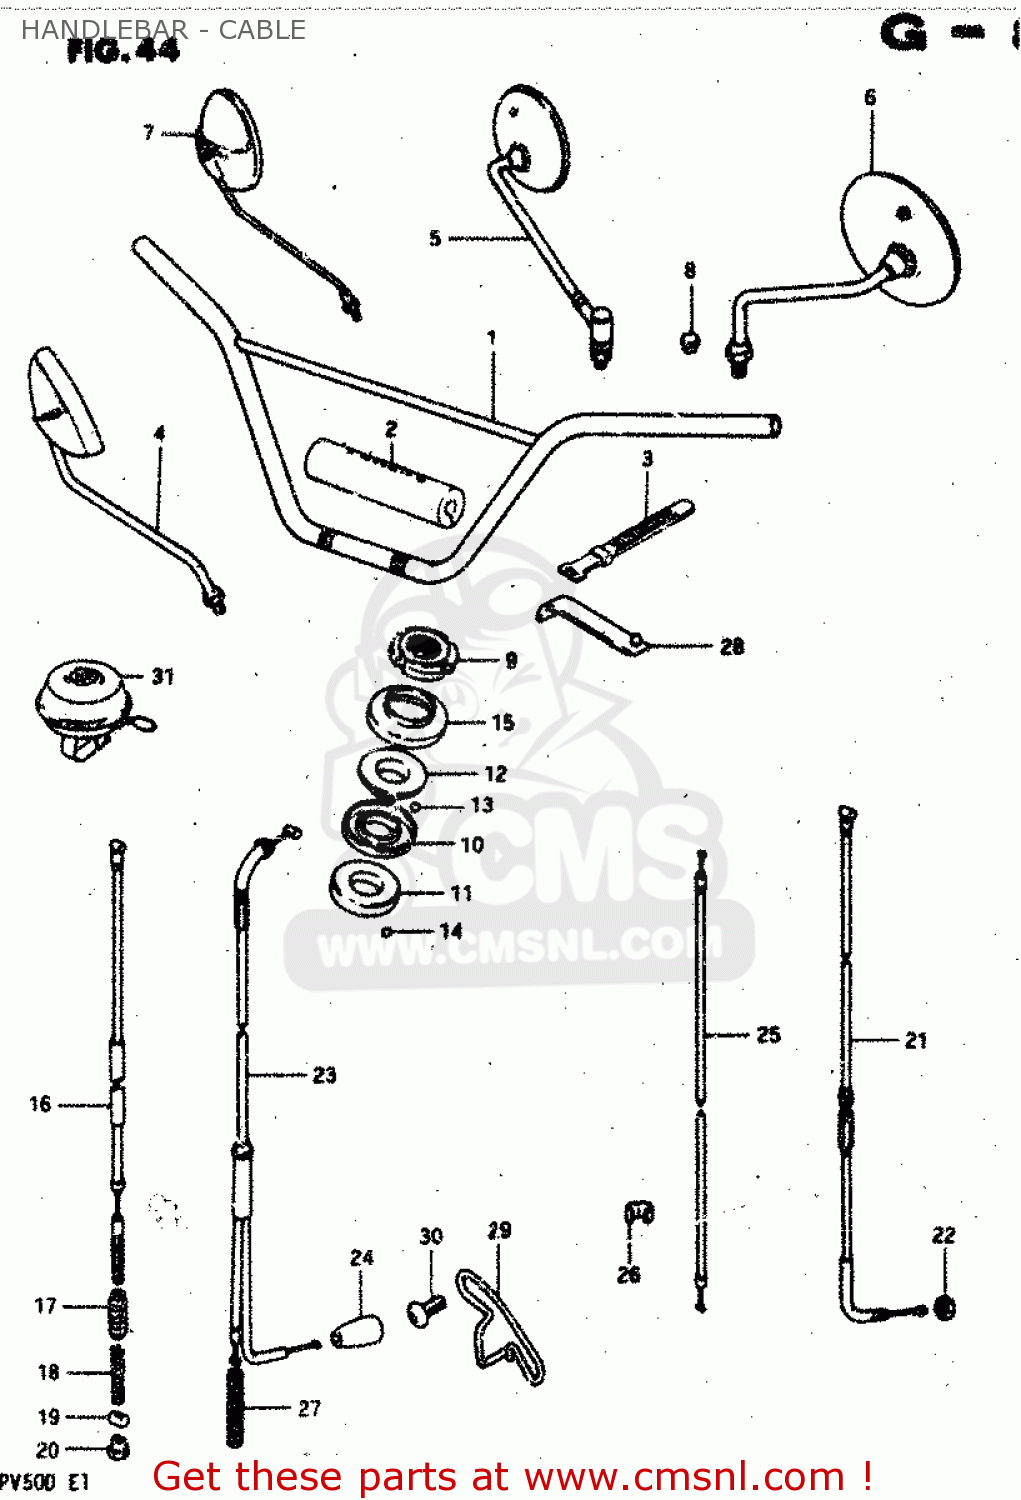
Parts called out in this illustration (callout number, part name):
1	HANDLE BAR
2	PAD,CROSSBAR
3	CLAMP(L:187)
4	MIRROR ASSEMBLY,RIGHT
5	MIRROR ASSY,RR VIEW
6	MIRROR ASSY, REAR VIEW
7	MIRROR ASSY, REAR VIEW
8	CAP
9	NUT,STEERING STEM(25X44X10)
10	RACE,STEERING INNER UPR
11	LACE,STEERING INNER LWR
12	RACE,STEERING OUTER UPR
13	BALL
14	BALL
15	DUST SEAL,STEERING UPR
16	CABLE ASSY,FR BRAKE
17	SEAL,DUST(7X16X75)
18	SPRING
19	PIN,10X19
20	NUT
21	CABLE ASSY, CLUTCH
22	NUT
23	CABLE ASSY, THROTTLE
24	SEAL,DUST(7X18X30)
25	CABLE, STARTER
26	CLIP
27	PROTECTOR,CABLE
28	BAND
29	GUIDE, CABLE
30	BOLT
31	BELL ASSY
